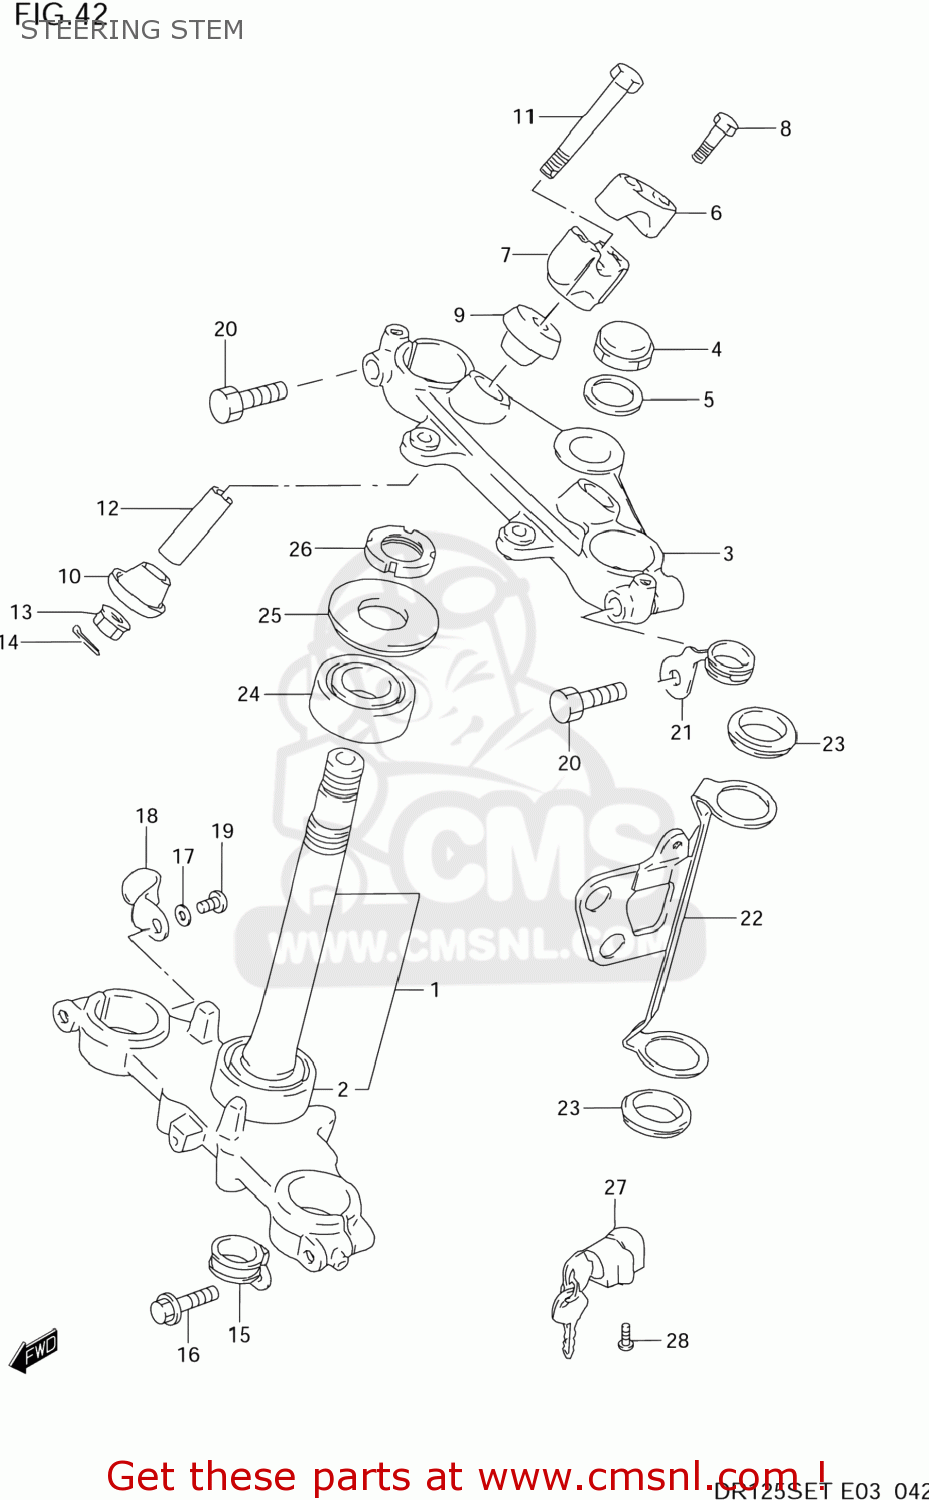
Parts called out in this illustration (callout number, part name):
1	STEM,STEERING (BLACK)
2	BEARING(30X55X17)
3	HEAD,STEERING STEM
4	NUT,CAP
5	WASHER
6	HOLDER,HANDLE UPR
7	HOLDER,HANDLEBAR LWR
8	BOLT
9	RUBBER,HANDLE HOLDER
10	RUBBER,LWR
11	BOLT,LWR HOLDER
12	SPACER
13	NUT
14	COTTER PIN
15	CLIP,LOWER
16	BOLT
17	WASHER,LOCK
18	CLIP
19	SCREW
20	BOLT
21	CLIP
22	BRACKET,HEADLAMP,R
23	CUSHION,HEADLAMP HSG BRACKET
24	TAPER,ROLLER BEARING
25	SEAL,STEERING UPR DUST
26	NUT,STEERING
27	LOCK SET,STEERING
28	SCREW
